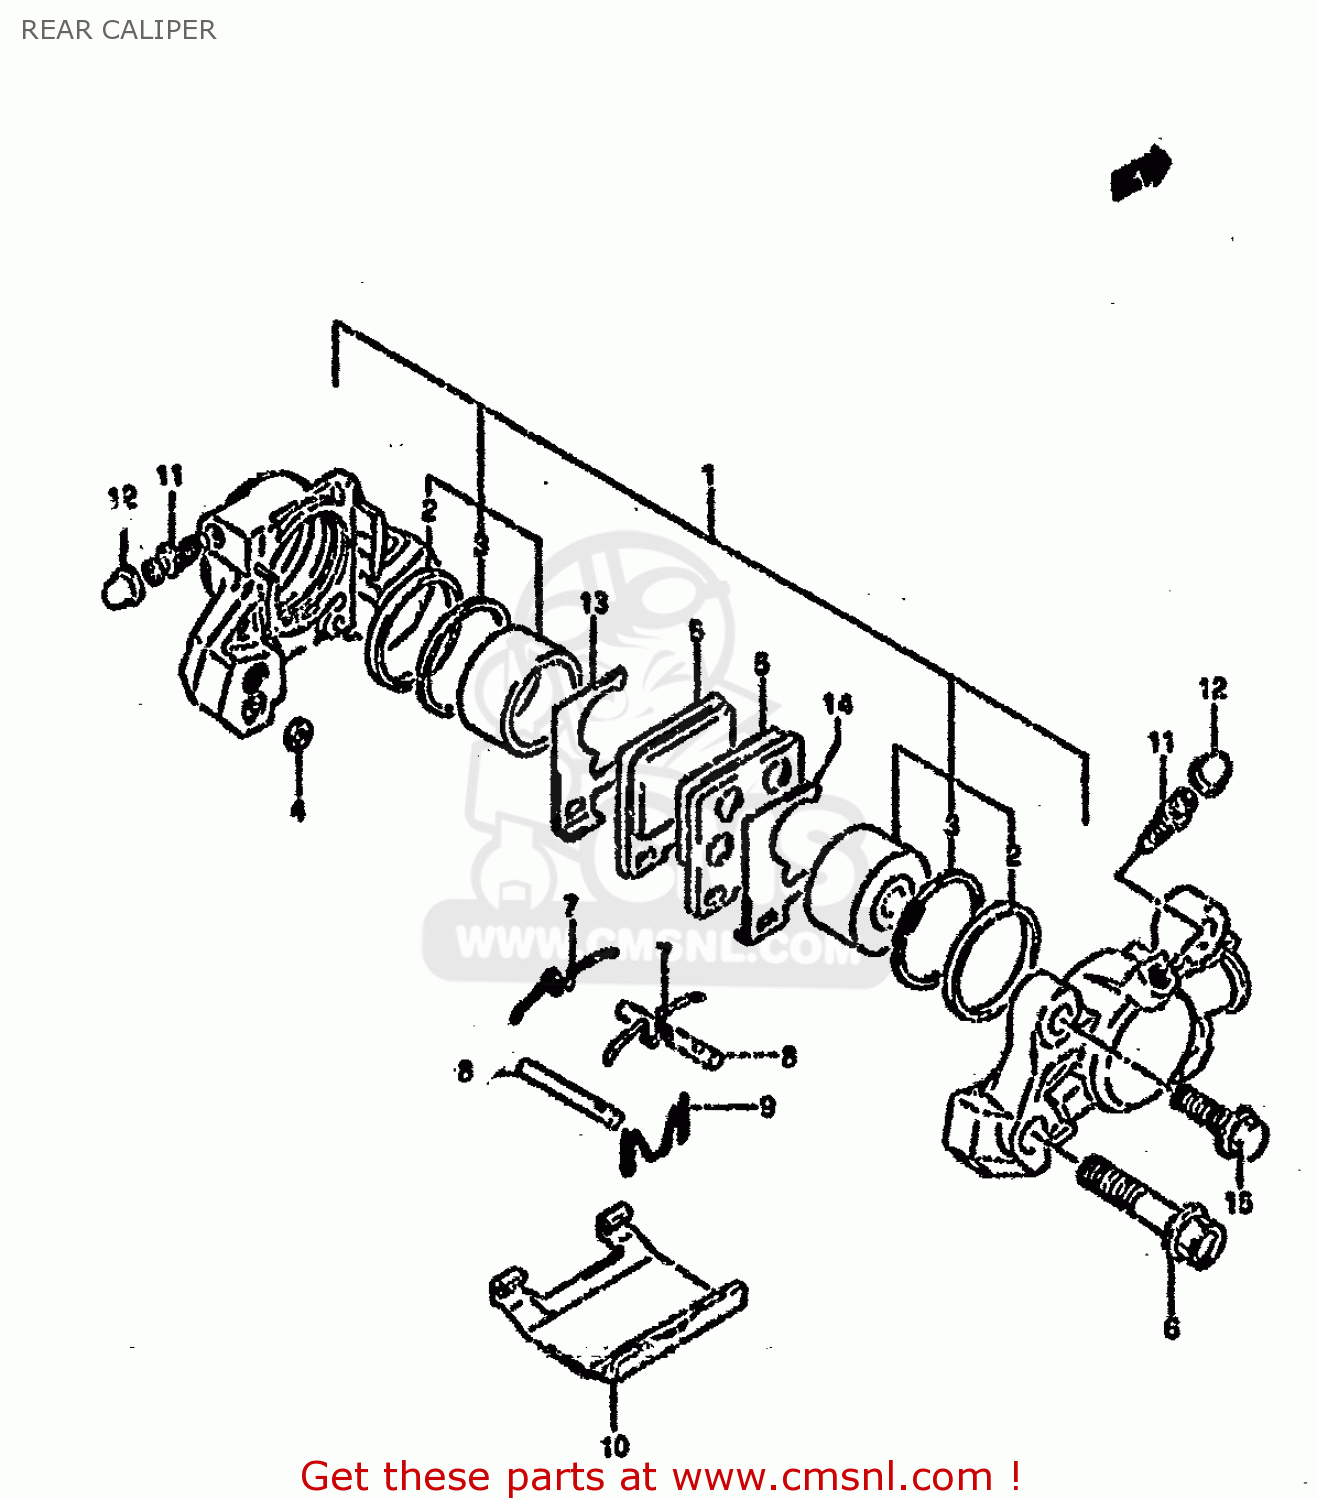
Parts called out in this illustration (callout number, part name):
1	PISTON SET
2	SEAL,PISTON
3	SEAL,WIPER
4	SEAL,JOINT
5	PAD,BRAKE
6	BOLT
7	SPRING
8	PIN,PAD
9	CLIP,PAD PIN
10	COVER
11	BLEEDER
12	CAP,BREATHER
13	SHIM,INNER
14	SHIM,OUTER
15	BOLT
